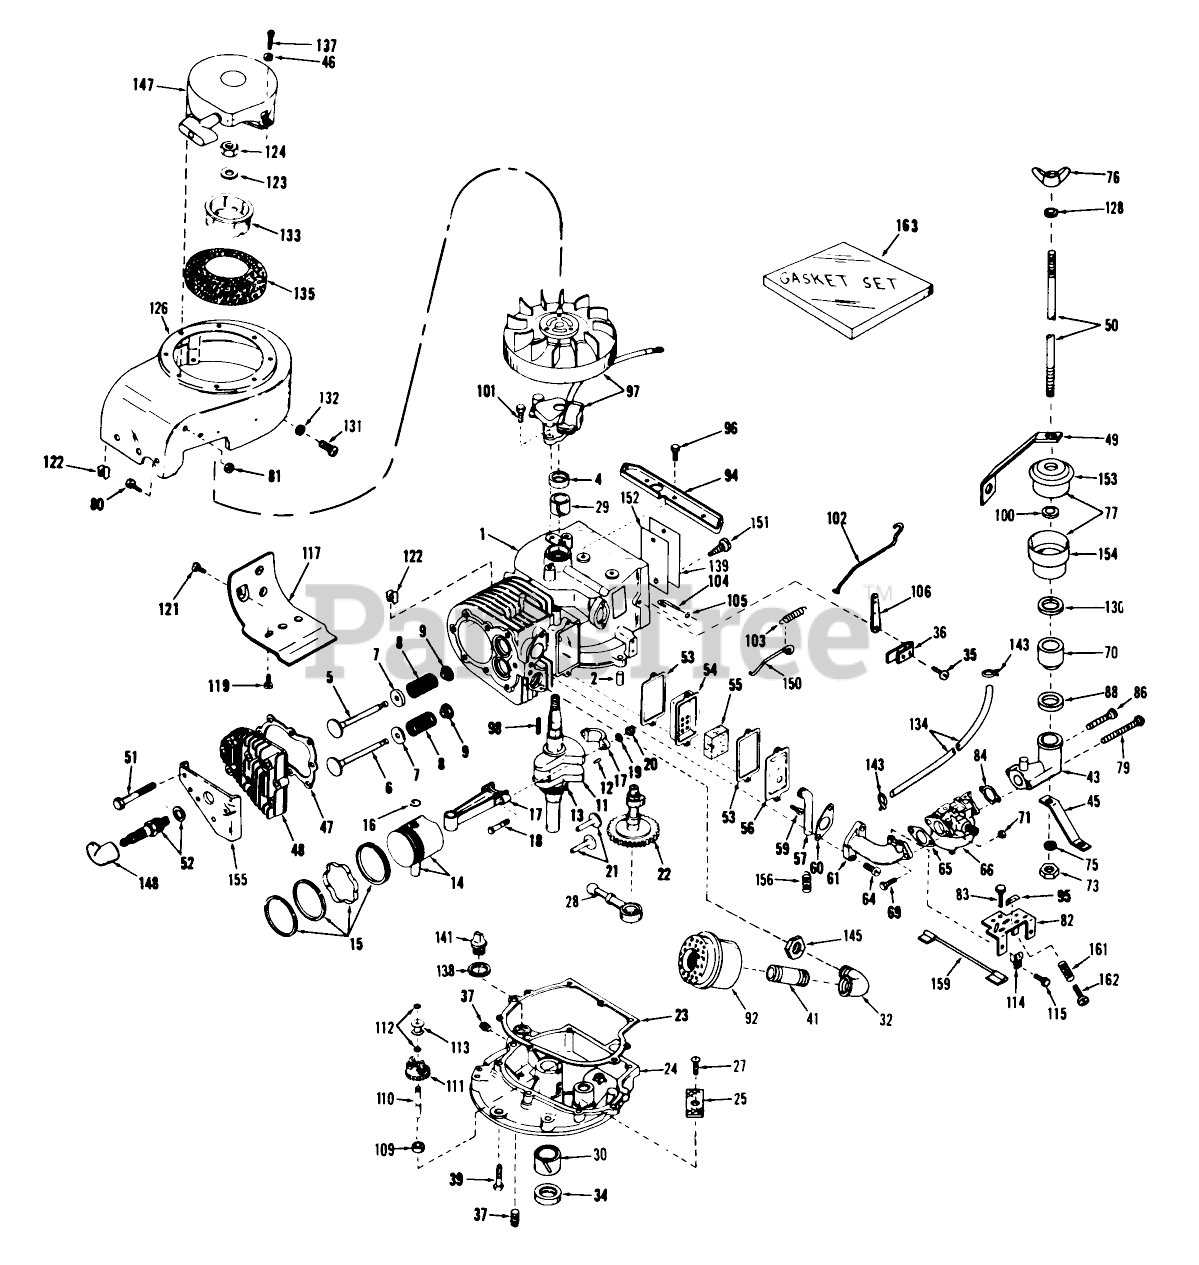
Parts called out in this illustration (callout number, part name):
1	Cylinder Assy.(Incl. Nos. 2 4)
2	Pin-Dowel
4	Seal, Oil
5	Valve, Intake, Standard (Incl. No. 9)
5	Valve, Intake, 1/32" Oversize (Incl. No. 9)
6	Valve, Exhaust, Standard (Incl. No. 9)
6	Valve, Exhaust, 1/32" Oversize (Incl. No. 9)
7	Cap-Spring, Valve
8	Spring-Valve
9	Keeper-Spring, Valve
11	Crankshaft Assy. (Incl. Ref. Nos.12 13) V40-50008E
11	Crankshaft Assy. (Incl. Ref. Nos.12 13) V40-50037E
12	Pin, Groove
13	Gear-Crankshaft
14	Piston Pin Assy., Std., (Incl. 2 of No. 16)
14	Piston Pin Assy., .010 oversize (Incl. 2 of No. 16)
14	Piston Pin Assy., .020 oversize (Incl. 2 of No. 16)
15	Ring Set (Standard)
15	Ring Set (.010 Oversize)
15	Ring Set (.020 Oversize)
17	Rod Assy., Connecting (Incl. Nos.18,19 20)
18	Bolt, Connecting Rod
19	Washer
21	Lifter Valve
22	Screw
23	Gasket-Cover, Cylinder
24	Flange Assy., Mounting (Incl. Nos. 25, 27, 34, 37, 43, 44 110)
25	Screen-Oil Filter
27	Screw
28	Pump, Oil
29	Bushing, Crankshaft
30	Bushing, Crankshaft
32	Elbow, Exhaust (90 degree)
34	Seal-Oil
35	Screw
36	Clamp-Lever, Governor
37	Plug-Drain, Oil (SQH 1/4-18)
39	Screw (1/4-20 x 1-1/4)
41	Nipple, Pipe
43	Elbow, Air cleaner
45	Brace, Cleaner elbow
46	Washer
47	Gasket-Head, Cylinder
48	CYLINDER HEAD
49	Brace Cleaner
50	Stud, Air cleaner
51	Screw
52	SPARK PLUG
53	Gasket-Breather
54	Body-Breather
55	Element-Breather
56	Cover-Valve
57	Tube-Breather
59	Screw
60	Gasket-Intake
61	Pipe, Intake
64	Screw (T-30, 5/16-18x1-3/32)
65	Gasket
66	Carburetor
70	Spacer, Cleaner
71	Nut and Lock Washer (1/4-28)
75	Lockwasher, Split
76	Nut-Wing
77	Cleaner Assy., Oil Bath Air (Incl. Nos.100,128,130,153 154)
79	Screw
80	Screw
81	Nut-Jam (5/16-24)
82	Control Assy., Speed
83	Screw (10-24 x 9/16)
84	Gasket
86	KIT - SEAL WIPER
88	Gasket, Spacer
92	Muffler
94	Bracket, Blower Housing (Incl. Nos. 131)
95	Decal
96	Screw (1/4-20x19/32)
97	Magneto
98	Key, Flywheel
100	O Ring
101	Screw
102	Link Governor
103	Spring Governor
104	Rod, Governor (Incl. Nos. 146)
105	Washer-Flat
106	Lever-Governor
109	Spacer
110	Shaft, Governor
111	Governor Gear ASM
112	Ring-Retaining
113	Spool-Governor
114	Conduit
115	Screw (10-32 x 3/8)
117	Emnsion, Blower Housing
119	Screw
121	Screw
122	51004 GIL ROTARY TI
123	Washer
126	Housing, Blower
128	Washer
130	1565F GIL TILLER.AD
131	Screw
132	Lockwasher
133	Cup-Starter
134	Line-Fuel
135	Screen, Air
137	Screw
138	Gasket
139	480B GIL SNWTHWR O/
141	Plug-Fill, Oil
143	Clamp-Line, Fuel
145	Nut, Conduit
147	Starter, Rewind
148	Cover-Spark Plug
150	Link Governor Spring
151	Stud
152	IDENTIFICATION PLATE
153	Cover, Oil bath cleaner
154	Bowl, Oil Bath Cleaner
155	Cover, Cylinder head
156	Spring, Coil
159	Wire, Ground
161	Spring-Compression
162	Screw
163	Gasket Set
